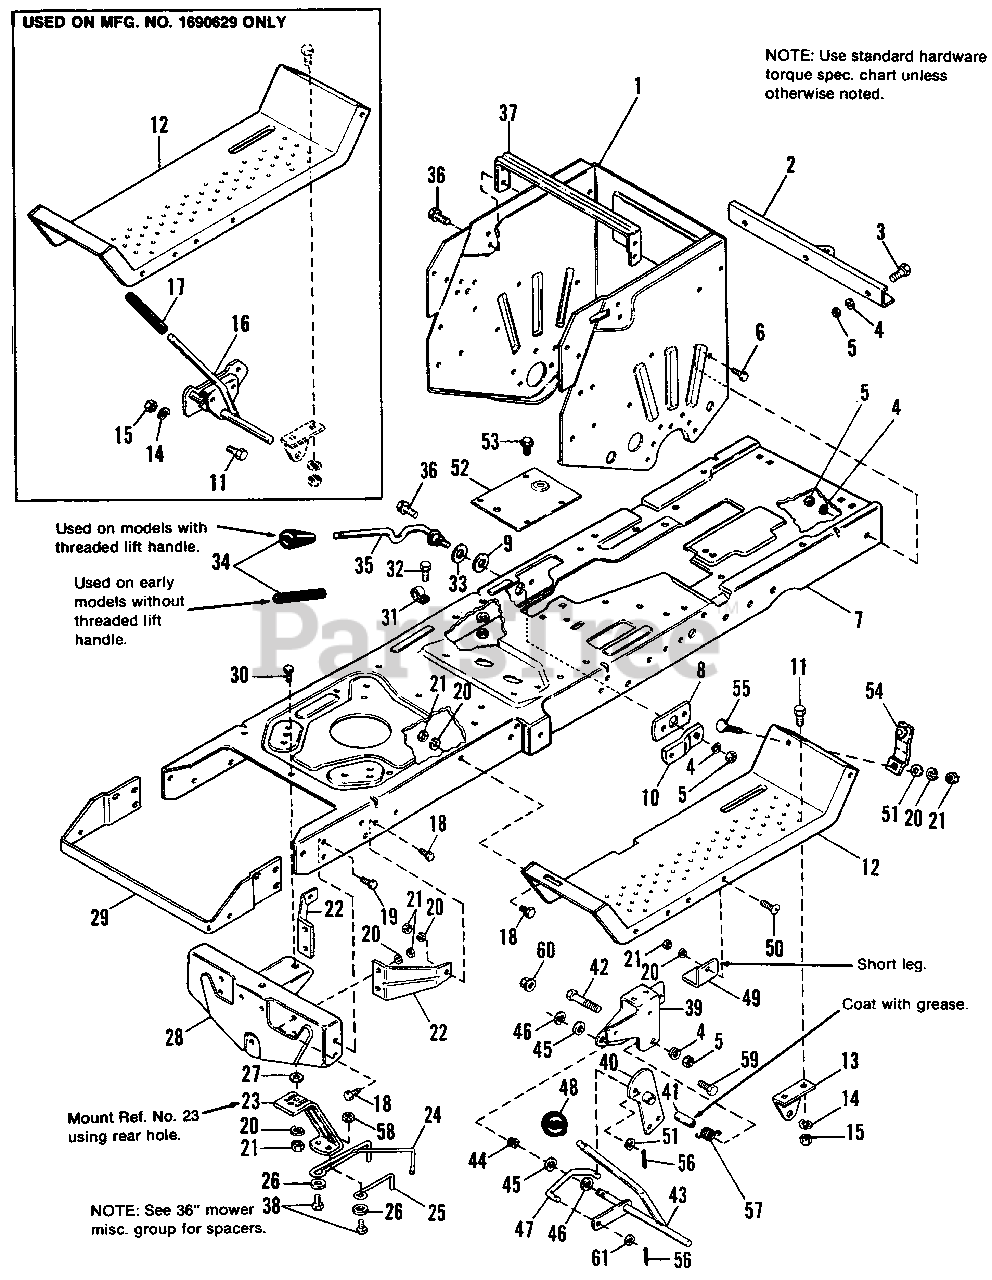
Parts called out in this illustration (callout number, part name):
1	SUPPORT, Axle, Wrapper (1690629 Only)
1	SUPPORT, Axle, Wrapper
2	BAR, Draw
3	CAPSCREW, Hex Hd., 3/8-16 x 1
4	LOCKWASHER, 3/8 (Qty. 10 used on 1690629)
5	NUT, Hex, Full, 3/8-16 (Qty. 10 used on 1690629)
6	CAPSCREW, Hex Hd., 3/8-16 x 3/4
7	FRAME (1690629 Only)
7	FRAME
8	BAR, Support
9	WASHER, Nylon
10	ARM, Support
11	CAPSCREW, Hex Hd., 1/4-20 x 5/8 (Qty. 4 on 1690629)
13	SUPPORT, Clutch
14	LOCKWASHER, 1/4 (Qty. 4 on 1690629)
15	NUT, Hex, Full, 1/4-20 (Qty. 4 on 1690629)
16	LEVER ASSY., Clutch (1690629 only)
17	GRIP, Handle (1690629 Only)
18	CAPSCREW, Hex Hd., 5/16-18 x 3/4
19	SCREW, Hex, Taptite, 5/16-18 x 3/4
20	LOCKWASHER, 5/16 (Qty. 22 used on 1690629)
21	NUT, Hex, Full, 5/16-18 (Qty. 22 used on 1690629)
22	BRACE, Axle Support
26	WASHER, Plain, 1/4
27	WASHER, Plain, 5/16
28	SUPPORT, Axle
29	SUPPORT, Hood
30	CAPSCREW, Hex Hd., 5/16-18 x 1-1/4
32	CAPSCREW, Hex Hd., 5/16-18 x 1-1/4
34	GRIP (used on models w/o threaded lift handle-1690629)
34	KNOB (used on models with threaded lift handle)
35	HANDLE, Lift
36	SCREW, Hex, Wash. Hd., Taptite, 5/16-18 x 1/2
37	BRACE, Seat
38	CAPSCREW, Taptite, 5/16-18 x 1-1/2
38	CAPSCREW, 5/16-18 x 7/8 (1690629 only)
39	BRACKET, P.T.O.
40	ARM ASSY., P.T.O. Rod
41	SPACER
42	CAPSCREW, Hex Hd., 3/8-16 x 2-1/4
43	HANDLE ASSY., P.T.O.
44	BUSHING
45	WASHER on P.T.O. Link
46	RING, Snap (Qty. 2 on 1690849, 1690879, 1690915, 1690934)
47	LINK, P.T.O.
48	KNOB
49	UP-STOP, Mower
50	SCREW, Truss Hd., Slotted, 5/16-18 x 3/4
51	WASHER
52	PLATE, Adapter
53	SCREW, Taptite, 1/4-20 x 1/2
54	LATCH ASSY.
55	BOLT, Carriage, 5/16-18 x 3/4
56	PIN, Cotter, 3/32 x 3/4
57	SPRING
58	NUT, Lock, 5/16-18
59	CAPSCREW, Hex, Wash. Hd., 1/4-20 x 5/8
60	NUT, Flange, Whizlock, 1/4-20
61	WASHER Plain
